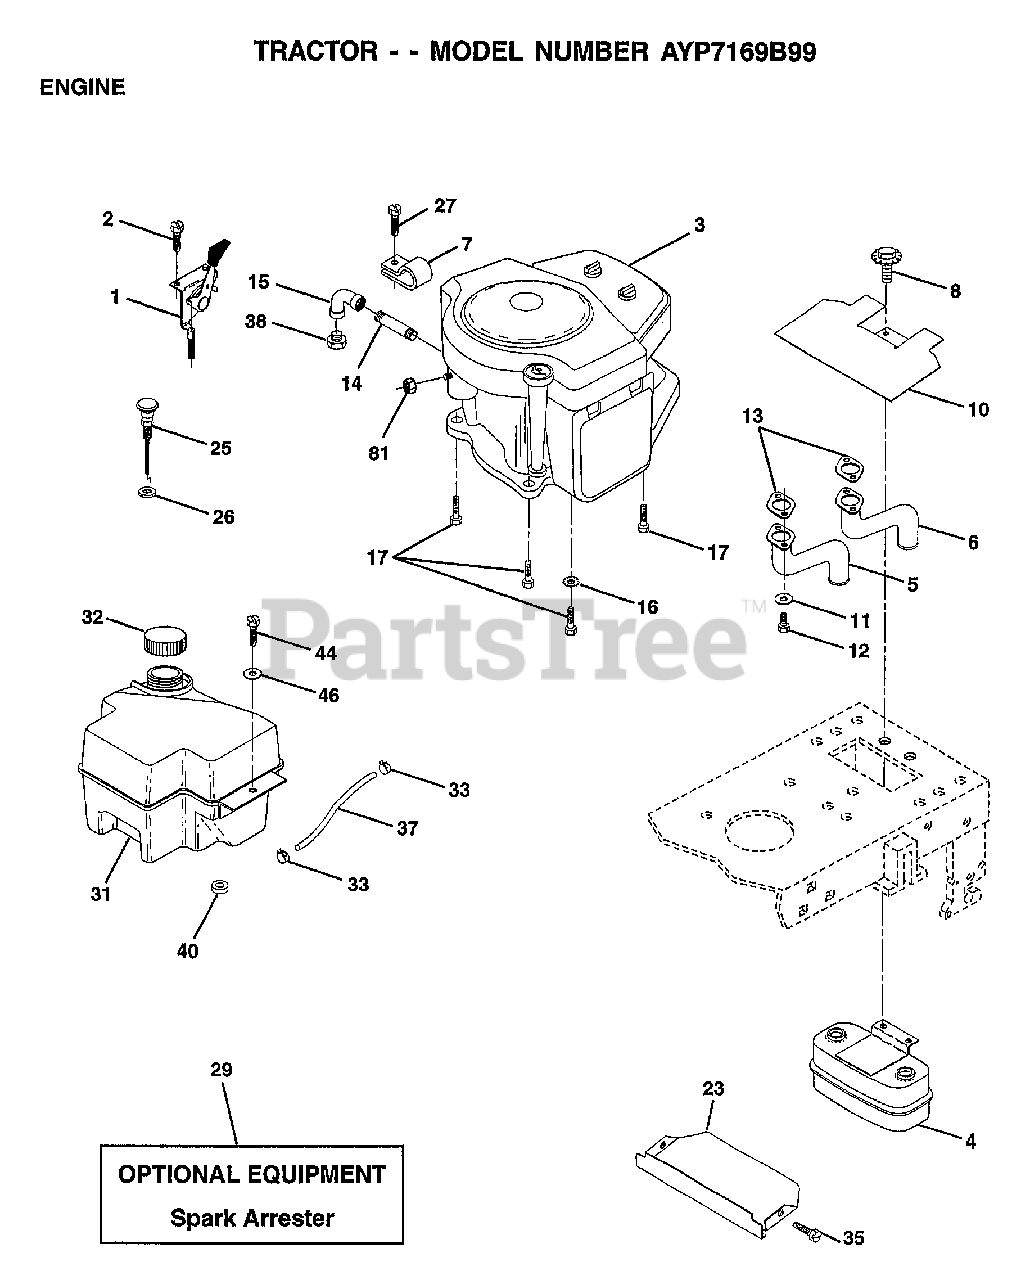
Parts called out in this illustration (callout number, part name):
1	CONTROL THRT 35.5
2	SCREW LT
4	MUFFLER.TW.LOTONE
5	EXHAUST.B&S.18.LH
6	EXHAUST.B&S.18.RH
7	CLAMP.TUBE.DBL.EN
8	BOLT.5/16-18.UNC
10	SHIELD.HEAT.
11	LOCKWASHER
13	GASKET MUFFLER
14	PIPE NIPPLE LT
15	ELBOW
16	LOCKWASHER
17	SCREW LT
23	SHIELD.BRN/DBR.GD
25	CONTROL.CHOKE.37
26	"NUT,KEPS 3/8-24IM"
27	"SCREW-TT,10-32 FL"
31	TANK.FUEL.FRONT.
32	CAP ASM FUEL
33	HOSE CLAMP
35	SCREW
37	LINE FUEL
44	SCREW HEX CRT
46	WASHER
81	NUT
